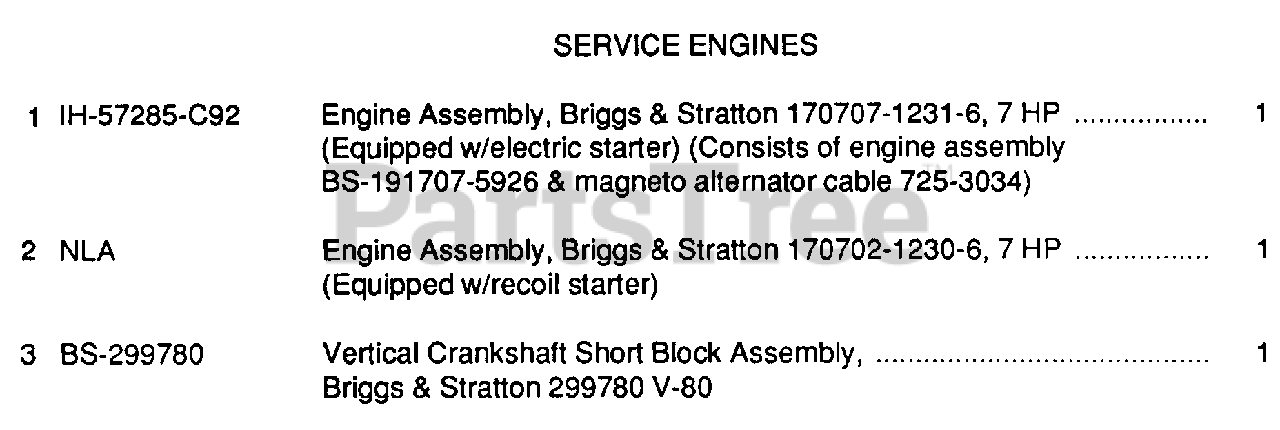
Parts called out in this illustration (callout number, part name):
1	Engine Assembly, Briggs & Stratton 170707-1231-6, 7 HP
2	Engine Assembly, Briggs & Stratton 170702-1230-6, 7 HP
3	Vertical Crankshaft Short Block Assembly
